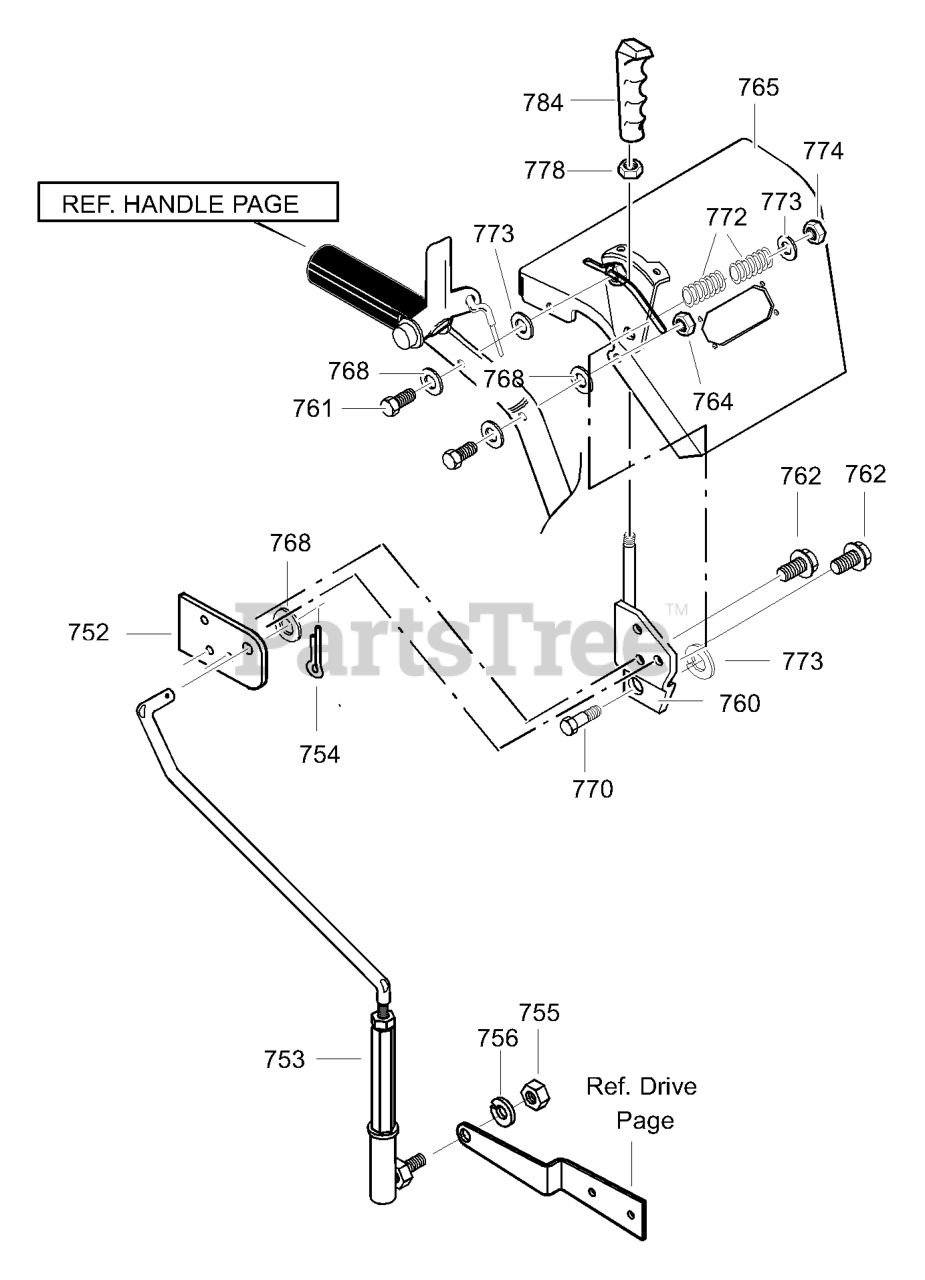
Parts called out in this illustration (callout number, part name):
752	BRACKET, CONTROL
753	ASSEMBLY, ROD
754	PIN, COTTER
755	NUT, 5/16-24
756	WASHER
760	HANDLE ASSY SPD CTRL
761	SCREW, 5/16-18 x 1.75
762	SCREW
764	NUT, 5/16-18
765	ASSY. BAY PANEL -LT
768	WASHER
770	SCREW 3/8-16X2.00
773	FLATWASHER
774	NUT, 3/8-16
778	NUT, 3/8-16
781	FLATWASHER
784	HANDLE, GRIP
813	RING, RETAINER
814	BEARING, FLANGE
